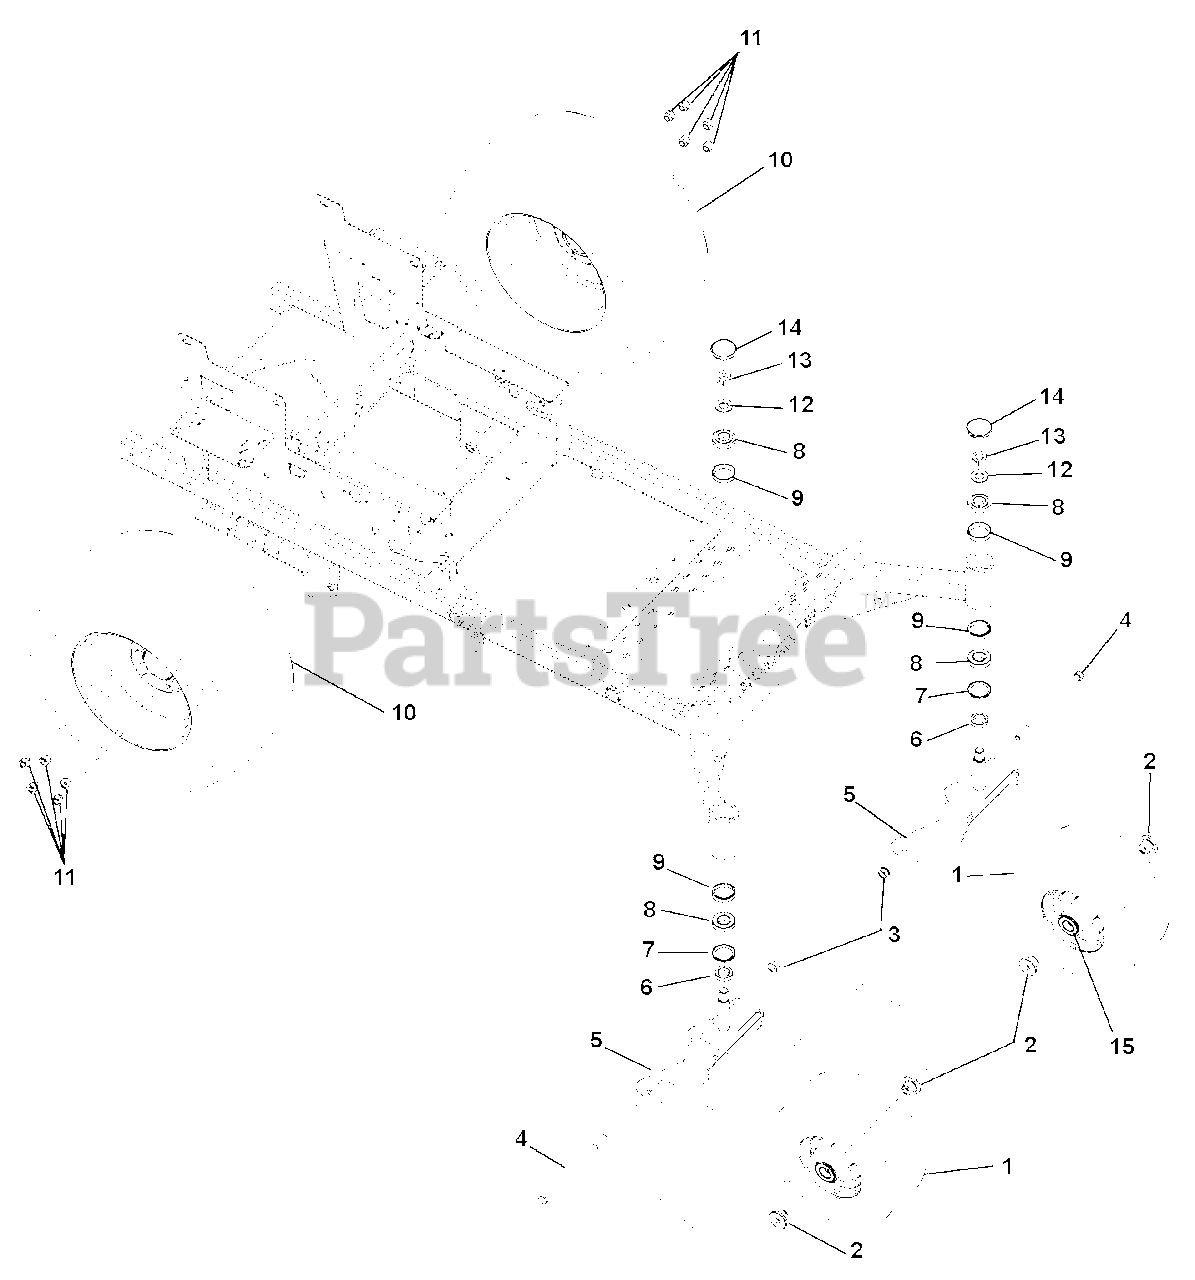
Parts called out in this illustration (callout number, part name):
1	Tire/Wheel Assembly, 13 x 6.50-6
2	Spacer, Front Wheel
3	Nut, Nyloc Flange .50-13
4	Bolt, Hex .50-13 x 9.00
6	Spacer 1.258 x 1.75 x .550
7	Seal, Oil 1.75 x 2.332 x .312
8	Bearing, Cone 1.25 x .66
9	Bearing, Cup 2.328 x .465
10	Tire/Wheel Assembly, 23 x 10.50-12
11	Nut, Wheel .50-20 13/16 Across Flats, Automotive Type
12	Washer, Flat Steel .812 x 2.00 x .148
13	Nut, Jam Center Lock .75-16
14	Cap, Dust
15	Bearing, 25 mm ID x 52 mm OD x 15 mm
